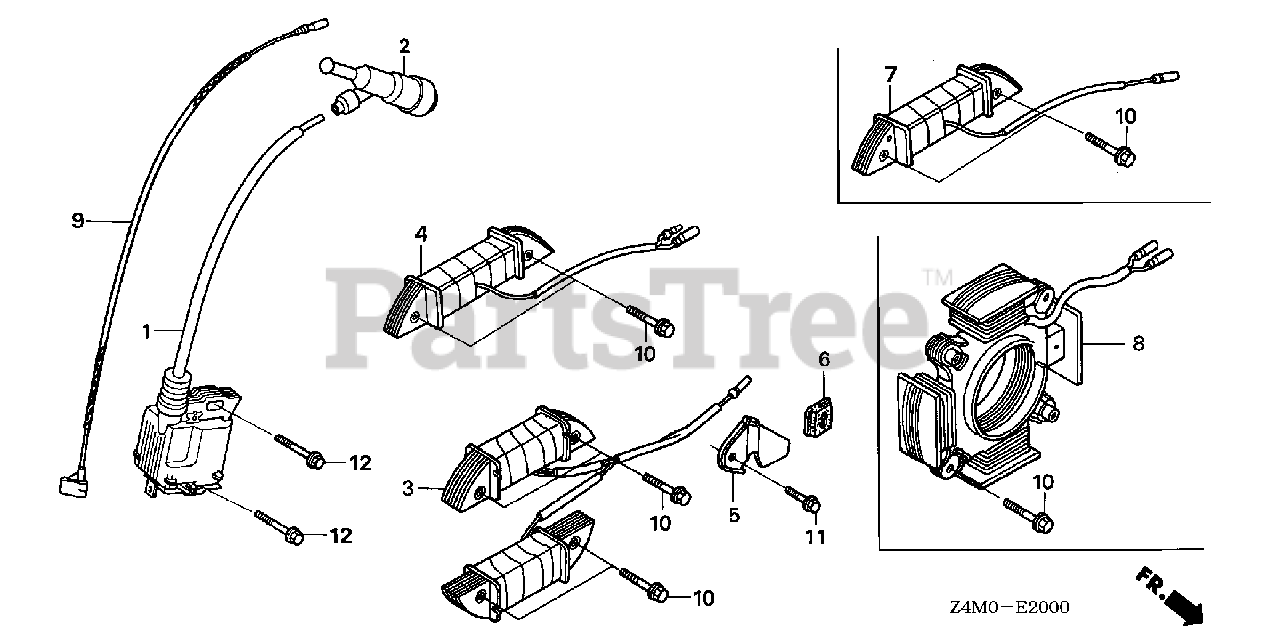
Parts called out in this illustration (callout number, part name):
1	COIL ASSY., IGNITION
2	CAP ASSY., NOISE SUPPRESSOR
9	WIRE, STOP SWITCH (370MM)
12	BOLT, FLANGE (6X25)
